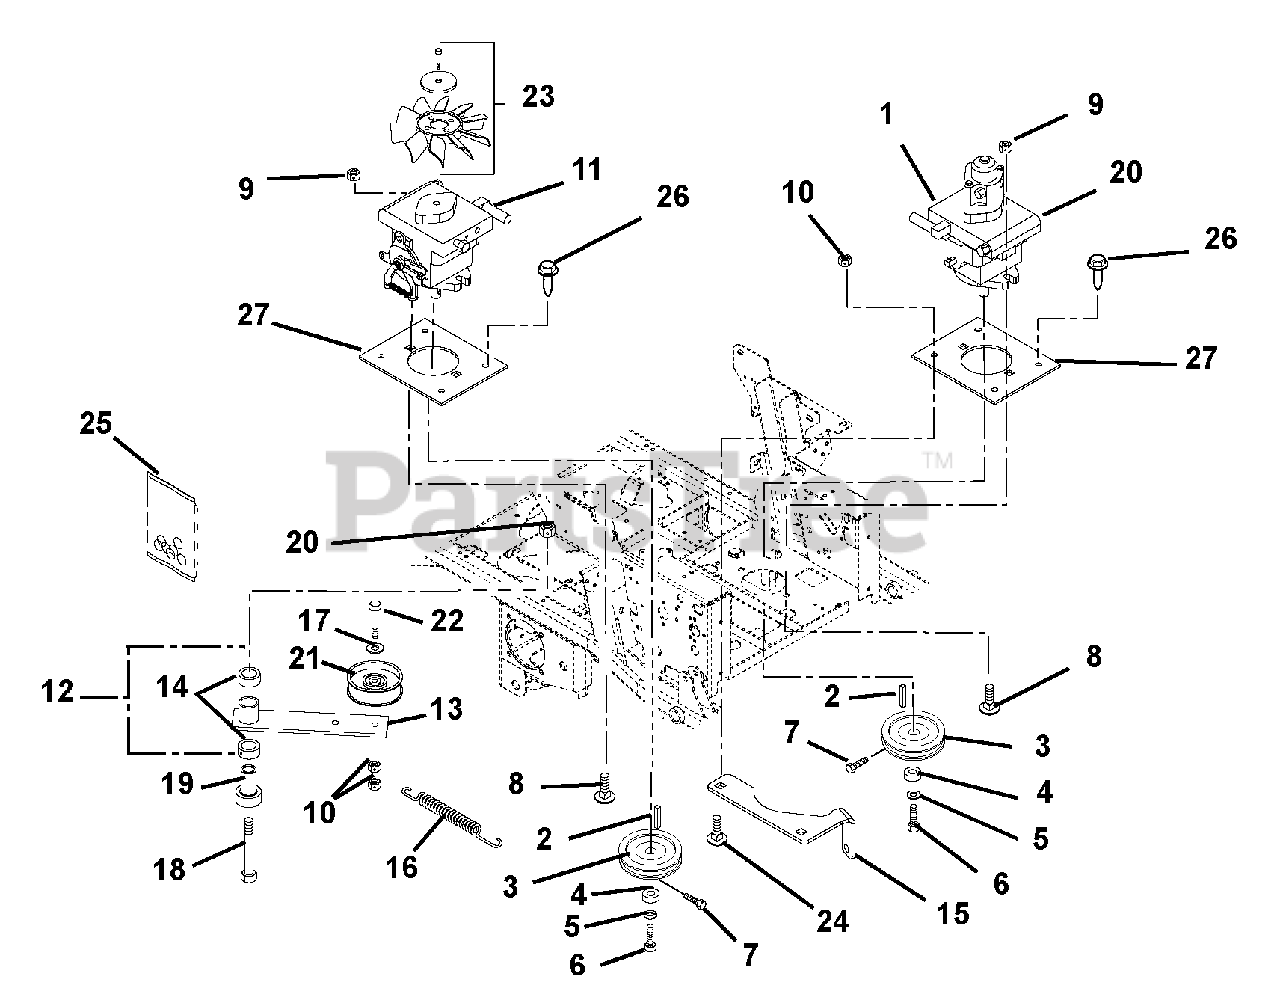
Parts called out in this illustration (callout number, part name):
1	Pump, Hydraulic
2	Key, Square 5 x 5 x 30mm Plain
3	Sheave, Poly-V .680 x 4.125 (12CC)
4	Washer, Flat Steel .281 x 1.0 x .063
5	Washer, Locking .25 x .062
6	Bolt, Hex M6 x 1.0 x 16
7	Screw, Socket Head .25-20 x .50
8	Bolt, Round Head Square Neck .44-14 x 1.50 Grade 5
9	Nut, Nyloc Flange .44-14
10	Nut-Locking-Top-Flange .38-16
11	Pump, Hydraulic PJ-Series 12CC (FAN)
12	Assembly, Idler Arm Guard Drive
13	Weldment, Idler Arm Ground Drive
14	Bearing, 1.00 x 1.12 x .75
15	Bracket, 12CC Pump Spring Anchor
16	Spring, Tension .120 x .845 x 6.500
17	Washer, Flat Steel .39 x .75 x.125
18	Bolt, Hex .50-13 x 3.50 Grade 5
19	Bearing, Pedestal
20	Nut, Locking Top Flange .50-13
21	Idler, Flat 4.00 x 0.38
22	Bolt, Hex .38-16 x 2.25 Grade 5
23	Fan, Cooling
24	Bolt, Round Head Square Neck .38-16 x 1.25 Grade 5
25	Kit, Pump Seal
26	Screw, Tapping .38-16 x .75 Hex Washer Head Thread Rolling
27	12CC Pump Mounting Plate
